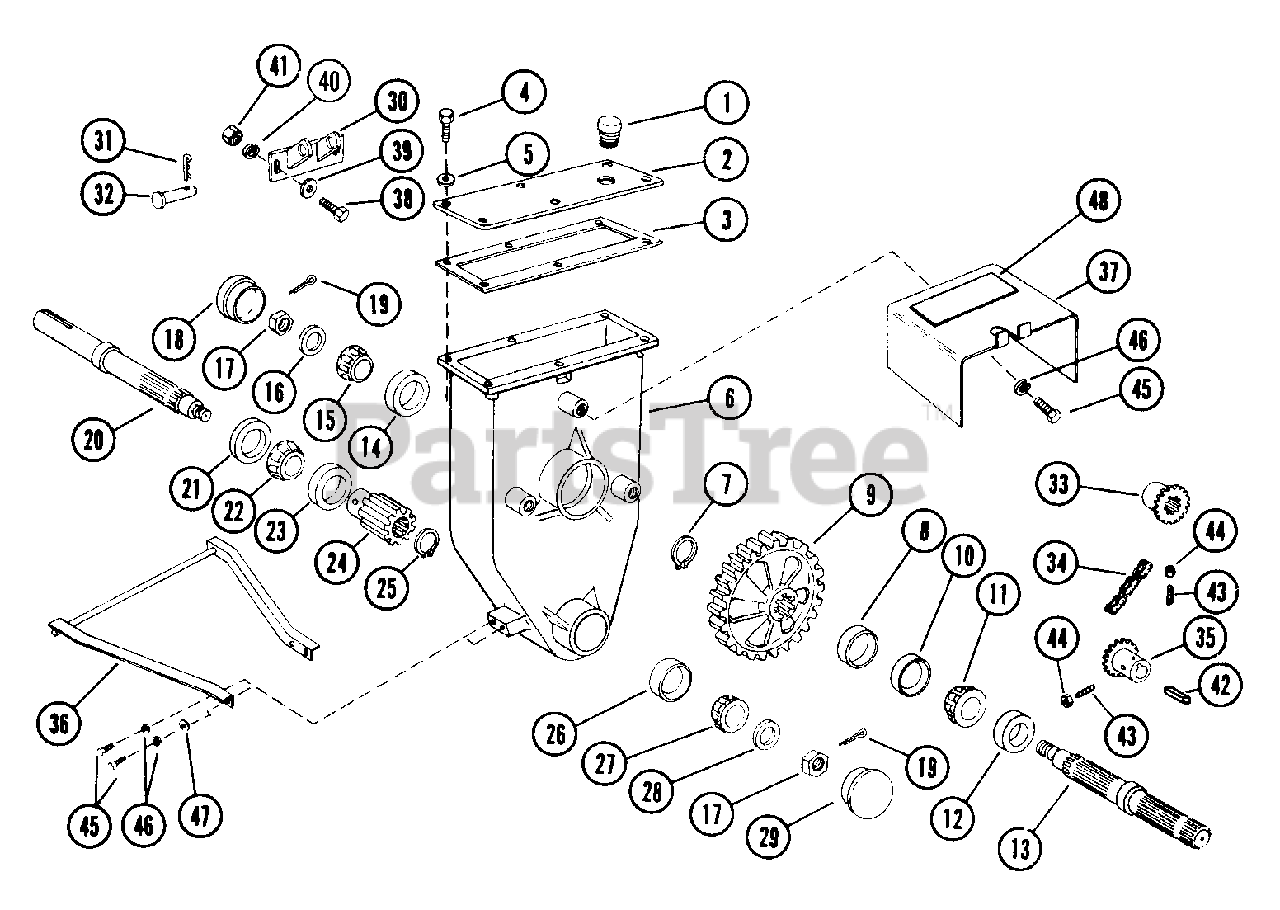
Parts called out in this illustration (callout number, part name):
1	AIR VENT
4	BLT-HEX .25-20X.50 PL GR2
5	WSHR-LK .250X.077 HVY PL
6	GEAR BOX
7	RG-RTNG-EXT 1.375X.050
8	SPACER 1.062X1.625X.375
10	BRG-CUP 2.563X.550
11	BRG-CONE 1.38X.72
12	SEAL 1.875X.625X.500
13	SHAFT ASSEMBLY
14	BRG-CUP1.980X.420
15	BRG-CONE 1.0X.58
16	WSHR-FL-STL .781X1.500X.188
17	NUT-JAM-SL .625-18
18	DUST CAP
19	PIN-COTR .12X1.0 PL
20	SHAFT ASSEMBLY
21	SEAL 1.500X2.265X.250
22	BRG-CONE 1.0X.81
23	BRG-CUP 2.441X.562
24	PINION GEAR
25	RG-RTNG-EXT 1.00X.042
26	BRG-CUP 1.781X.475
27	BRG-CONE .750X.61
28	WSHR-FL-STL.812X1.500X.139
31	PIN-HAIR INT .09X.188 PL
32	PIN-CLEV .619X2.0 YWZC
34	ROLLER CHAIN
35	SPROCKET
38	BLT-HEX .38-16X1.00 PL
39	WSHR-FL-STL .438X1.0X.083 PL
40	WSHR-LK .375X.094 MED PL
41	NUT-HEX .375-16
42	KEY-SQ .25 X 2.50 X .25 SAE
43	SCR-SET .32-18X.75 SQHCUP PL
44	NUT-JAM .312-18 PL
45	BLT-HEX .31-18X1.25 PL GR2
46	WSHR-LK .312X.097 PL HVY
47	WSHR-FL-STL .38X.875X.083 PL
48	DECAL CAUTION
